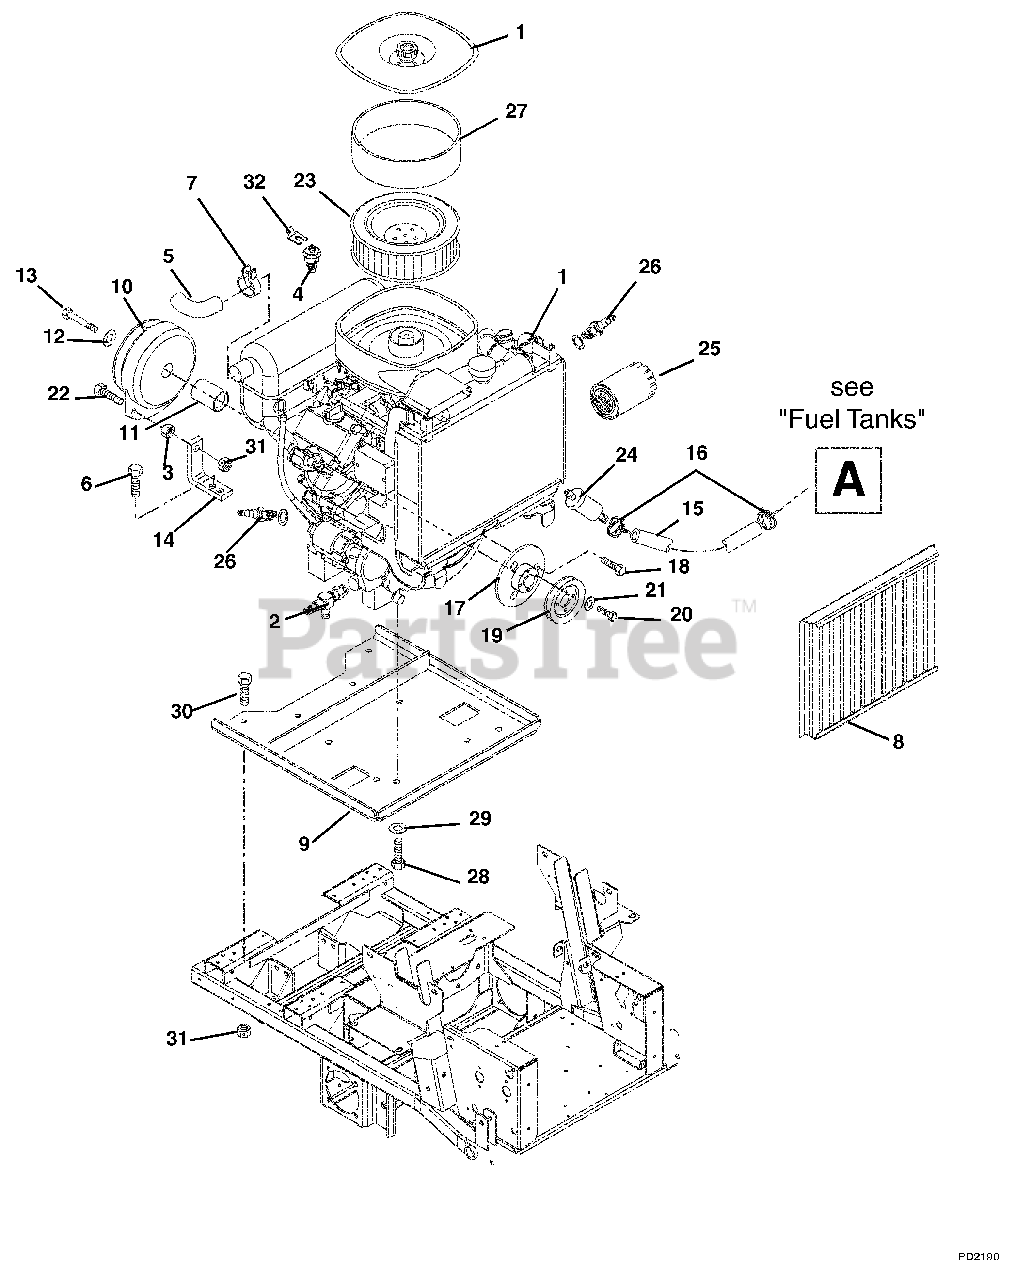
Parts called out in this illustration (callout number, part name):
1	Engine, 27HP Gas Kawasaki
2	Drain, Oil
3	Nut-Jam .312-18
4	Temperature Sender
6	Screw-Tapping .38-16 x .75 Hex Washer Head
7	Clamp, Muffler Assembly
9	Weldment, Engine Plate
10	Clutch, Electric
11	Spacer, Clutch
12	Washer-Locking .44 x .109
13	Bolt-Hex M10 x 1.5 x 60 8.8
14	Anchor-Clutch
15	Gas Line-Bulk .25 ID
16	Clamp-Hose Wire .490/.510 x .116
17	Adapter, Sheave (Kawasaki)
18	Bolt, M8-1.25 x 25
19	Sheave, Poly-V 1.0 x 3.25
20	Bolt-Hex .25-20 x .50 Grade 5
21	Washer-Locking .25 x .062 Regular
22	Bolt-Hex .31-18 x 1.50 Grade 5
23	Air Filter
24	Fuel Filter
25	Oil Filter
26	Spark Plug
27	Element, Precleaner
28	Bolt-Hex M10 x 1.5 x 25
29	Washer-Locking .44 x .109 Regular
30	Bolt-Hex .31-18 x 1.00 Grade 5
31	Nut-Locking-Nylon .312-18
32	Male Disconnect Adapter
